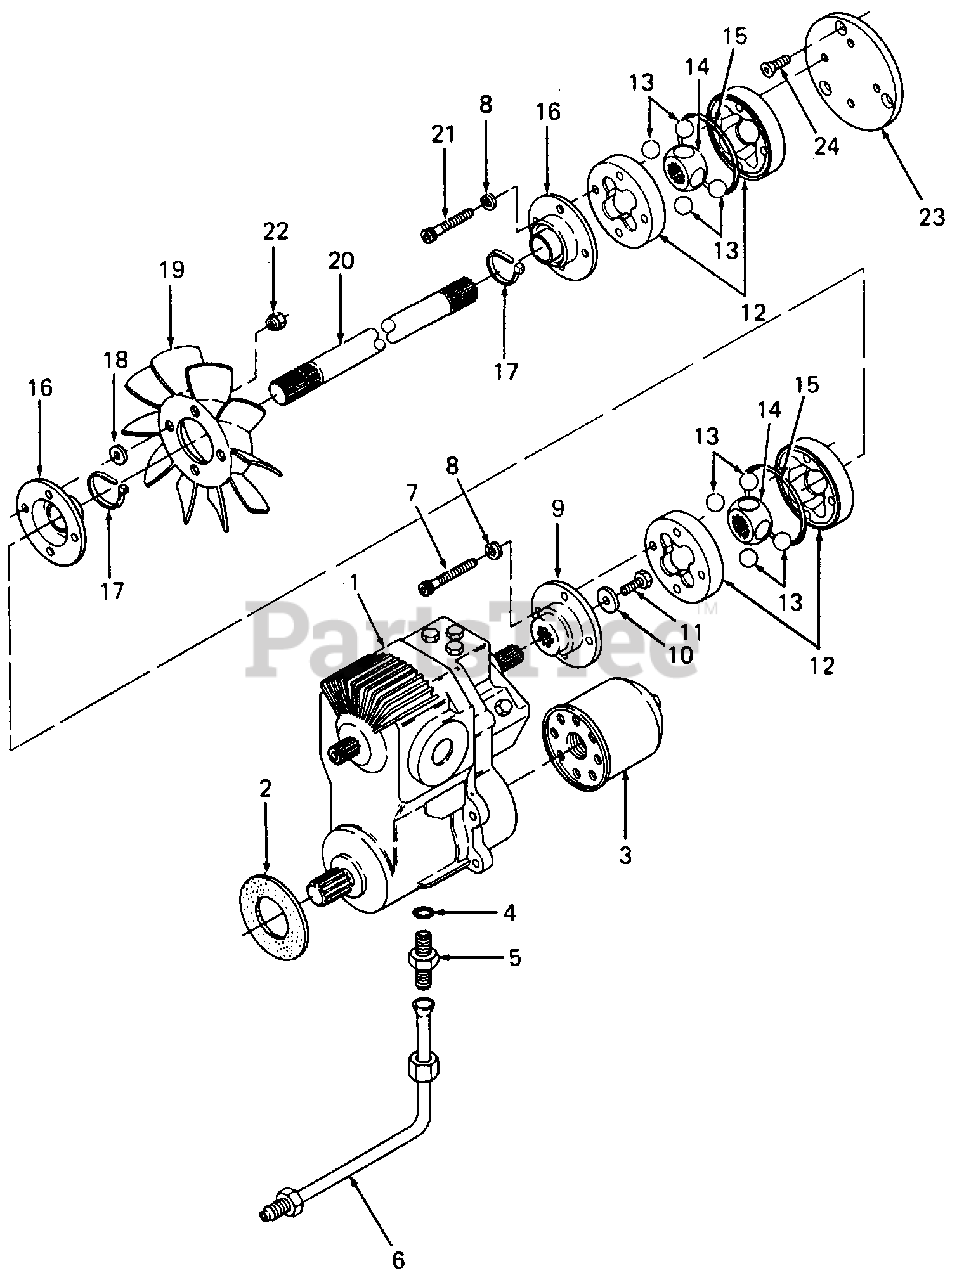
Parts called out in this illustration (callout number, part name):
1	Pump, Hydrostatic
2	Gasket, Front
3	Filter, Oil
4	O-Ring, 5/8 OD Tube
5	Connector, 37 Degree
6	Tube Assy
7	Screw, Socket Hd Cap, 1/4-20 X 2.0 Lg
8	Washer, Lock, 1/4
9	Adapter, Pump
10	Washer, Bell, .265 X .75 X .062 Thk
11	Screw, Hex Patch, 1/4-20 X 1.0 Lg GR5
12	Coupling, Drive w/O-Ring Groove
13	Ball, Steel, 5/8 Dia Chrome
14	Hub, Drive
15	O-Ring, 2.489 X. 070
16	Boot, Coupling
17	Strap, Tie
18	Washer, Flat, .25 X .62 X .052 Thk
19	Fan, 10 Blade Hydro
20	Shaft, Drive, 22.88 Lg
21	Screw, Hex Patch, 1/4-20 X 1.62 Lg GR5
22	Nut, Fan, 1/4-20
23	Fitting, Grease
24	Plate, Coupling Adapter
